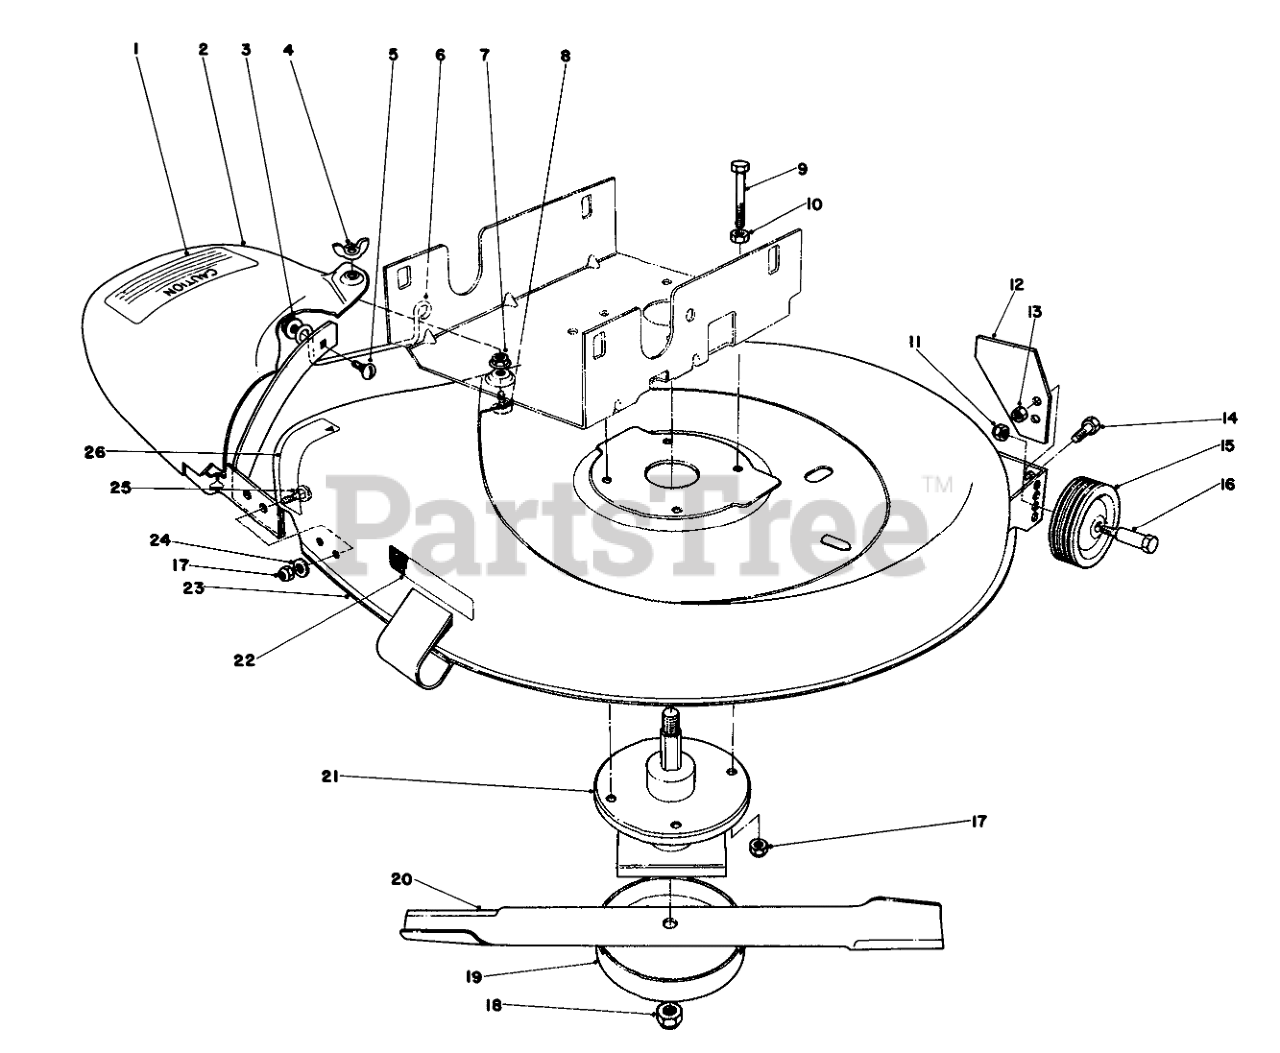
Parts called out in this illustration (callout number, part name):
1	Decal
2	DEFLECTOR WA R
3	NUT-LOCK, HHF
4	Wing Nut
5	SCREW-CARRIAGE
6	Bracket Foot Guard
7	PAL NUT
8	Carriage Bolt
9	SCREW-HH
10	NUT-JAM
11	Nut
12	Deck Stop
13	NUT-LOCK, CONE
14	SCREW-HH
15	Wheel
17	NUT-LOCK, CONE
19	Cup
20	Blade
21	Mower Spindle
22	Decal-Deck Inst.
23	HOUSING WA R
24	WASHER-FLAT
25	BOLT-CARR
26	Decal Housing
